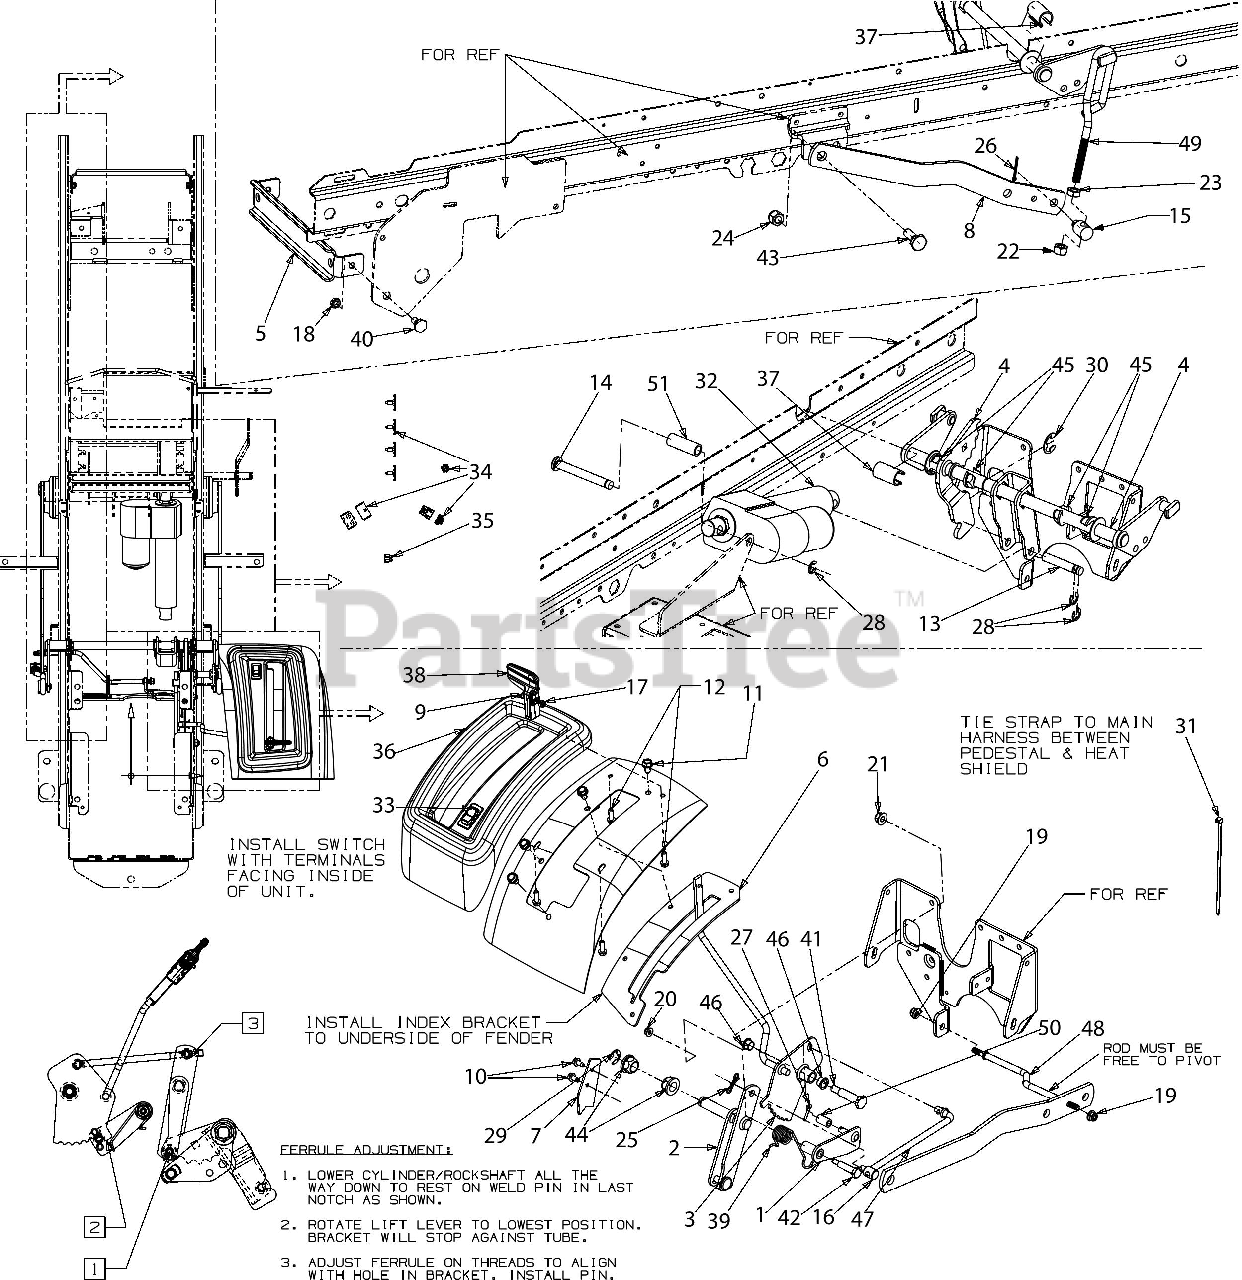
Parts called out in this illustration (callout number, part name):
1	HEIGHT LEVER ARM
2	HEIGHT SETTING ARM
3	HEIGHT POSITION LEVER
4	LIFT SHAFT ASSEMBLY ELEC LIFT
5	FRONT HANGER BRACKET
6	HEIGHT INDEX BRACKET
7	HEX BEARING STOP PLATE
9	SCREW #10-24 x .62
10	SCREW 1/4-20 X.500
11	SCREW 5/16-18 x .625
12	SCREW 1/4-15 x .750
13	PIN .495 x 2.75
14	LIFT ACTUATOR PIN
15	LIFT LINK FERRULE
16	FERRULE 3/8-24 x .375
18	JAM LOCK NUT
19	FLANGE LOCK NUT 5/16-18
20	FLANGE LOCK NUT
22	HEX NUT NYLOK 1/2-13
23	HEX NUT
24	HEX LOCK NUT NYLON
25	BOW TIE COTTER PIN 1/4-5/16
26	COTTER PIN
27	COTTER PIN
28	E-RING FOR .500
30	RETAINING RING
31	7" CABLE TIE
32	ACTUATOR LIFT
33	PLOW LIFT SWITCH
34	DECK LIFT HARNESS
35	FUSE-30 AMP
36	FENDER COVER-ELECTRIC LIFT (RH)
37	SNAP SPACER .75
38	CUTTING HEIGHT KNOB
39	TORSION SPRING
40	SHOULDER SCREW .500 DIA x .295
41	SHOULDER BOLT .498 x 1.635:3/8-16
42	SHOULDER SCREW .374 DIA. x 1.375 LG
43	SHOULDER BOLT
44	FLANGE BEARING
45	HEX FLANGE SPLIT BEARING
46	NYLINER BEARING
47	ADJUSTMENT LIFT ROD
48	DECK ANTI SWAY ROD
49	LIFT ADJUSTMENT LINK
50	SPACER .35X.50X.891 LG
51	SPACER .551X.750X2.06LG
